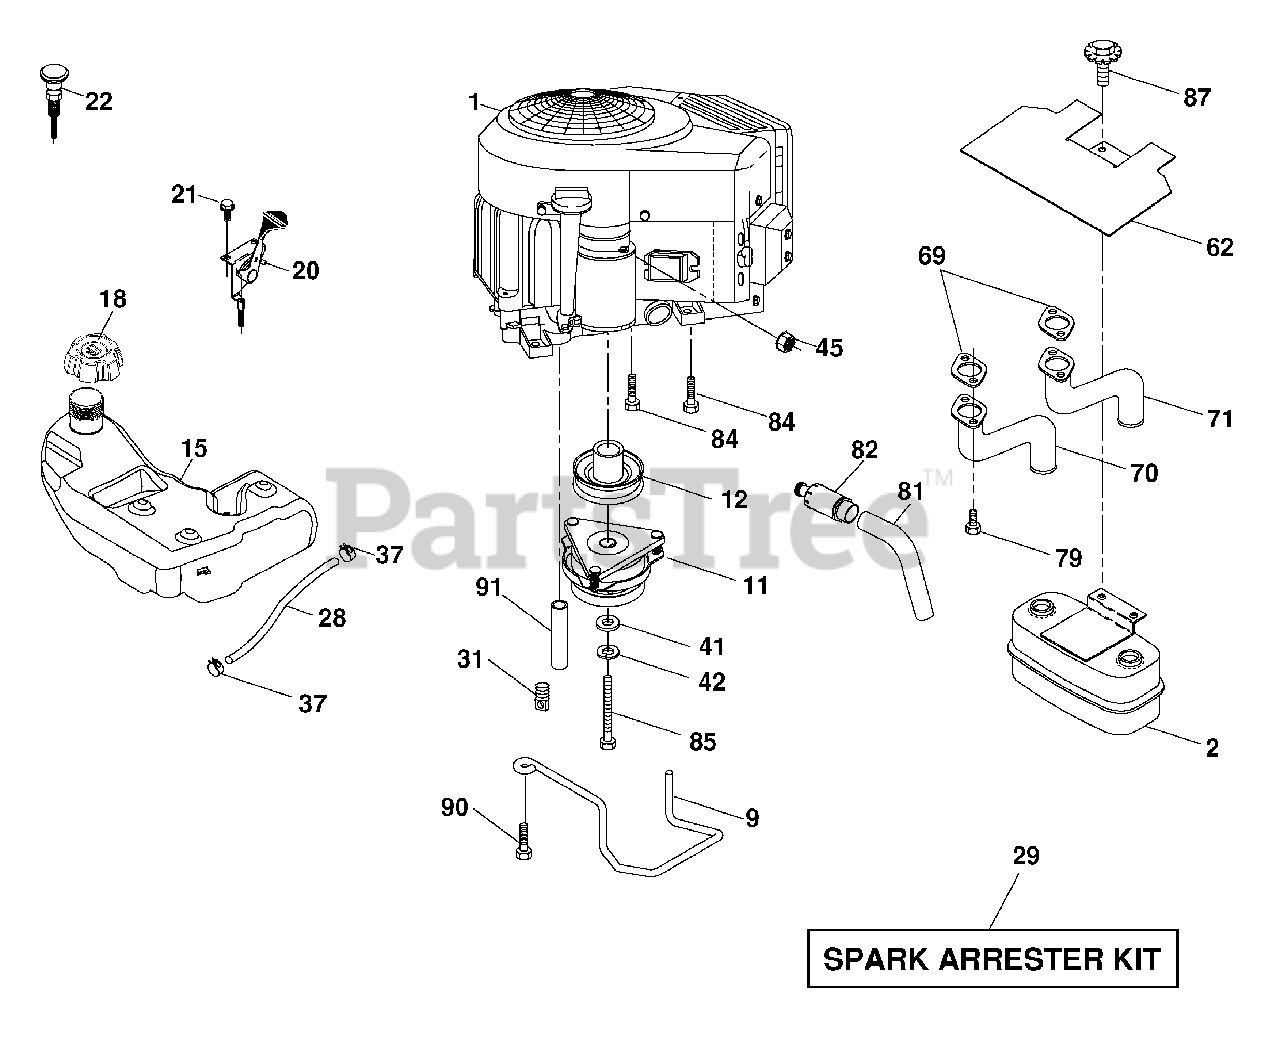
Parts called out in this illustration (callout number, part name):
1	Engine Briggs
9	Keeper Belt Engine
11	Clutch Electric
12	Pulley Engine
15	Tank Fuel 4.0
18	Cap Asm
20	Control Throttle
21	Screw 10 x 3/4 Single Lead Hex
22	Control Choke
28	Fuel Line
29	Spark Arrester Kit
31	Clip Push-In
37	Clamp Hose
41	Washer 1-1/2 OD x 15/32 ID x .250
42	Washer Lock 7/16
45	Nut Keps Hex 1/4-20 unc
62	Shield Heat Muffler
70	Tube Exhaust LH
71	Tube Exhaust RH
79	Screw Socket Head 5/16-18 x 1
81	Tube Drain Oil Easy
82	Plug Drain Oil
84	Screw 3/8-16 x 1-1/4
85	Bolt Hex 7/16-20 x 3.75 Gr. 5
87	Bolt 5/16-18 unc x 1 w/Sems
90	Screw 3/8-16 x 1
